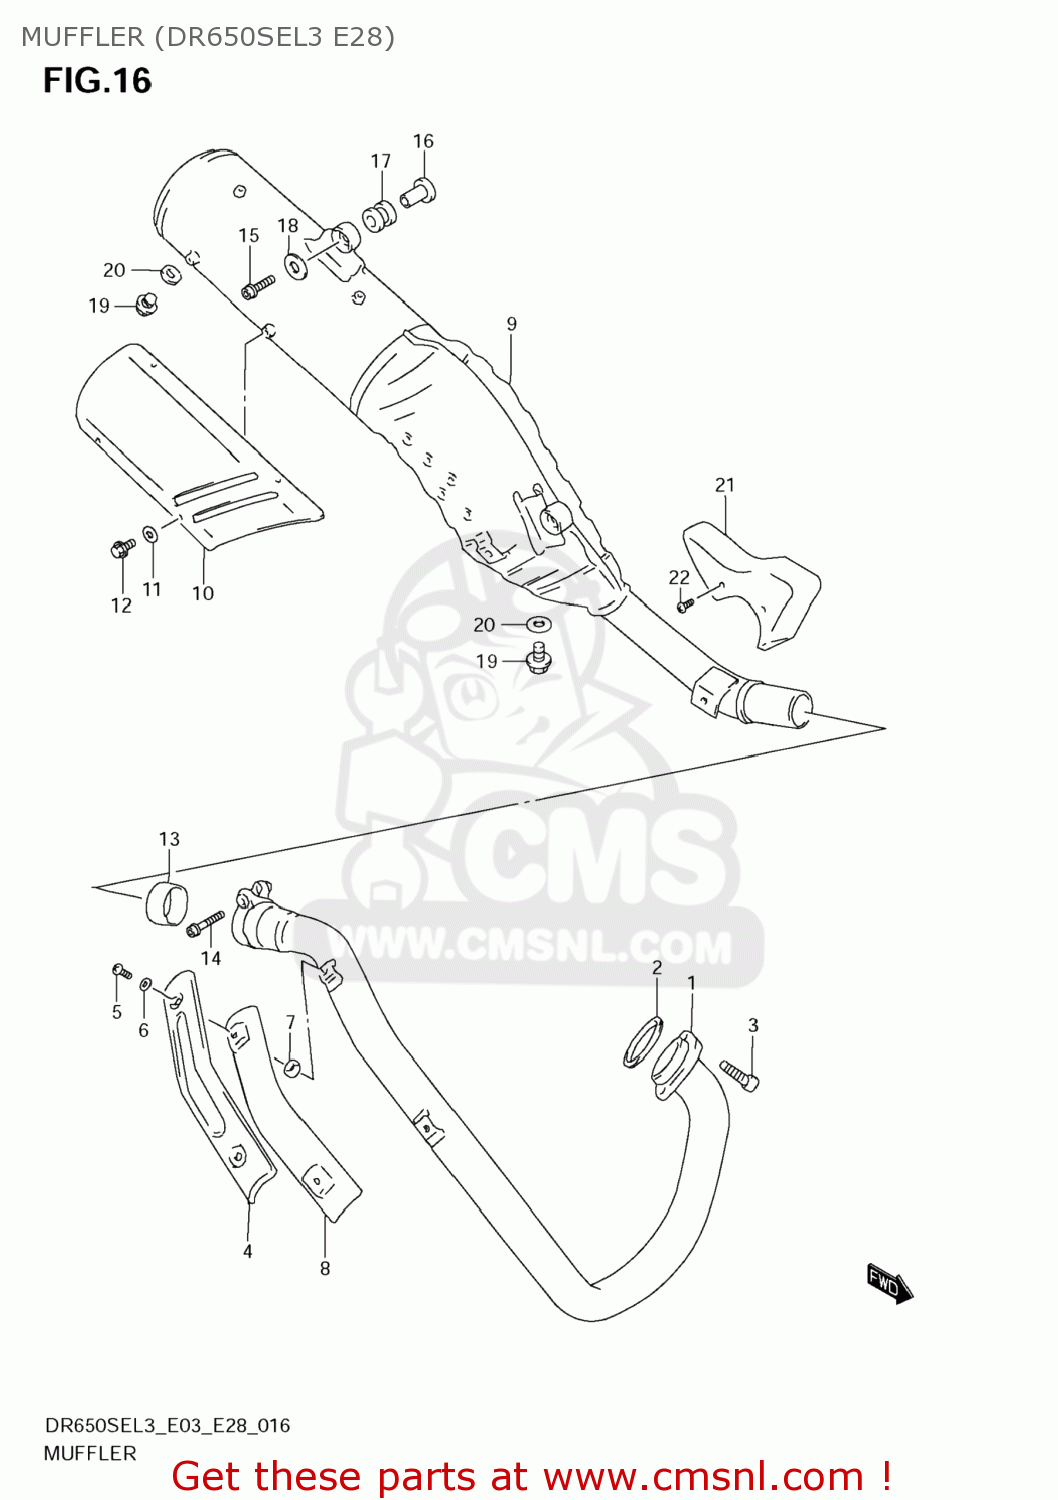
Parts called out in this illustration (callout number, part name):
1	PIPE,EXHAUST
2	GASKET,EXHAUST PIPE (NAS)
3	BOLT
4	COVER,EXHAUST PIPE
5	SCREW(6X12)
6	WASHER(6.5X13X1.0)
7	GASKET(6X16X1.4) (NAS)
8	COVER,EXHAUST PIPE INNER
9	BODY,MUFFLER
10	COVER,MUFFLER
11	WASHER(6.5X13X1.0)
12	SCREW(6X10)
13	CONNECTOR,MUFFLER
14	BOLT
15	BOLT(8X30)
16	SPACER(8.6X12X17.5)
17	CUSHION
18	WASHER(8.5X28X1.6)
19	PLUG(12X9)
20	GASKET(12.1X16.2X3.7) (NAS)
21	COVER,CONNECTOR CLAMP
22	SCREW(6X10)
